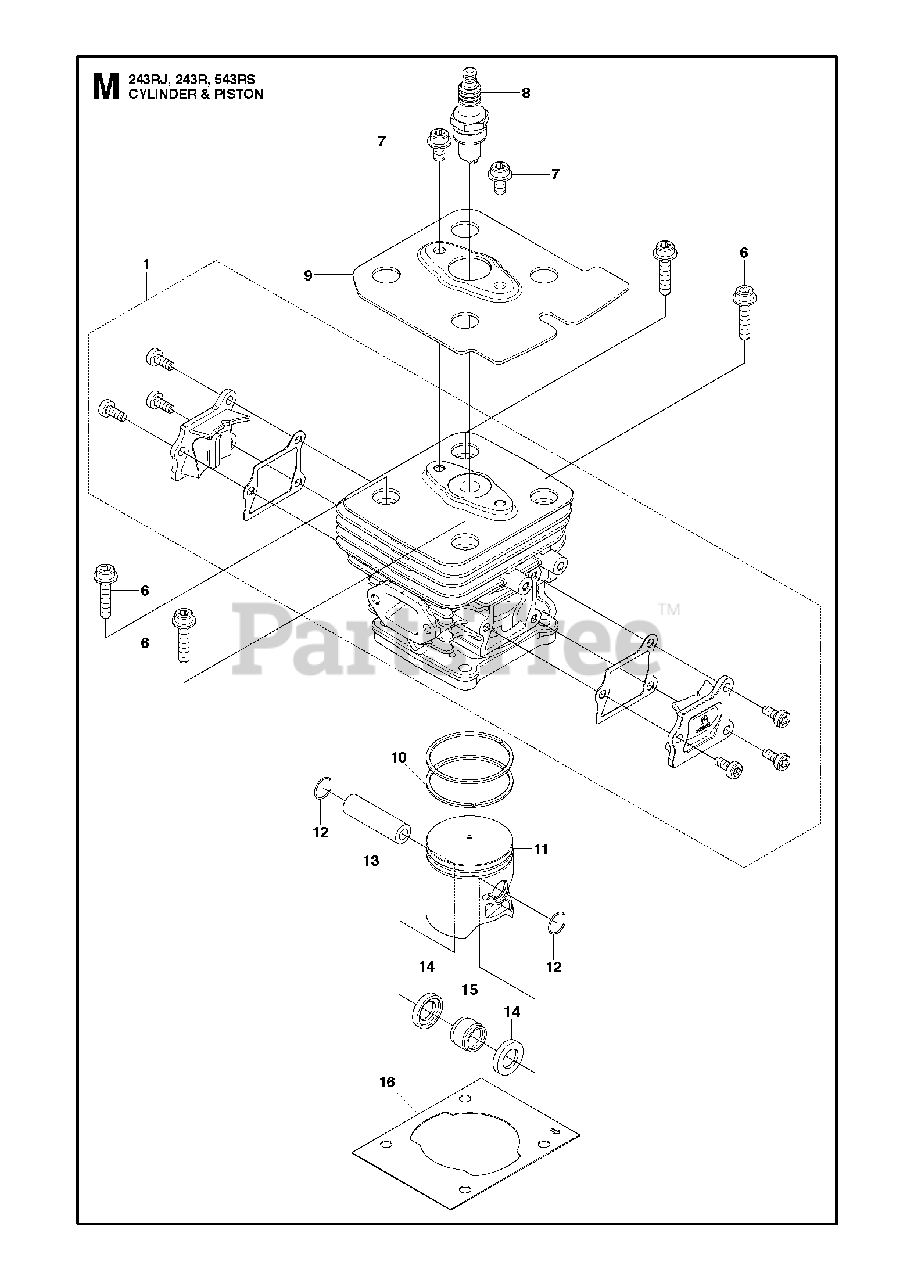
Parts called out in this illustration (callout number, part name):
1	CYLINDER-COMP 848GG01211
1	CYLINDER COMP
7	BOLT (RPLS T495051010-11)
8	SPARK PLUG CMR7H-10
9	PLATE
10	RING PISTON
11	PISTON 848GG041A0
11	PISTON
15	ROLLER BEARING
